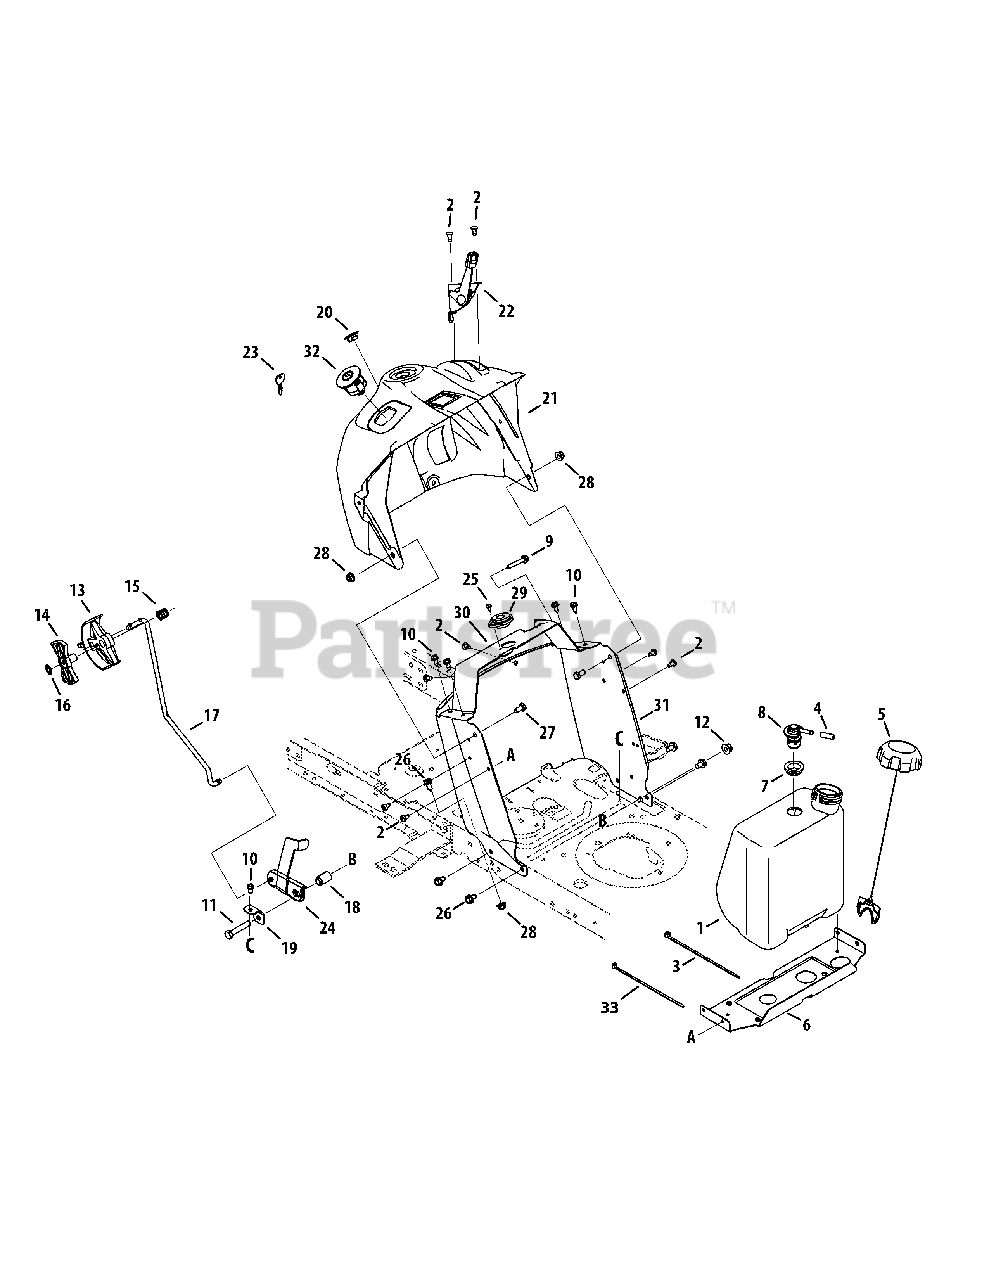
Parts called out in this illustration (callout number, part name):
1	Fuel Tank, 1.36 Gal.
2	Screw, Tap, 1/4-20, 0.500
3	Cable Tie, 36.0 Long
4	Hose Vent
5	Fuel Cap, 2.25"
6	Gas Tank Support Bracket
7	Rubber Grommet, 23 x 3.55
8	Rollover Valve
9	Hex Screw, 1/4-20 x 1.50
10	Tap Screw, 1/4-20, 0.625
11	Hex Screw, 3/8-16, 2.00, Gr5, Std
12	Flange Lock Nut, 3/8-16
13	Shift Lever
14	Index Control, 6 Speed
15	Compr. Spring, .685 OD x .63
16	Lock Washer, 1/4
17	Speed Selector Control Rod
18	Flng Spacer, .390 X .671 X 1.095
19	Speed Latch
20	Choke Plug
21	Dash, Upper
22	Throttle/Choke Cable Assembly
23	Key, Assembly
24	Speed Latch - No RMC
25	Screw, #10-16 x .500
26	Tap Screw,5/16-18, 0.625
27	Hex Screw, 5/16-18 x .625
28	Flange Lock Nut, 5/16-18
29	Bearing, .628 ID x 1.36
30	Bracket, Steering Support
31	Dash, Lower NWNDW
32	Key Switch
33	Cable Tie
